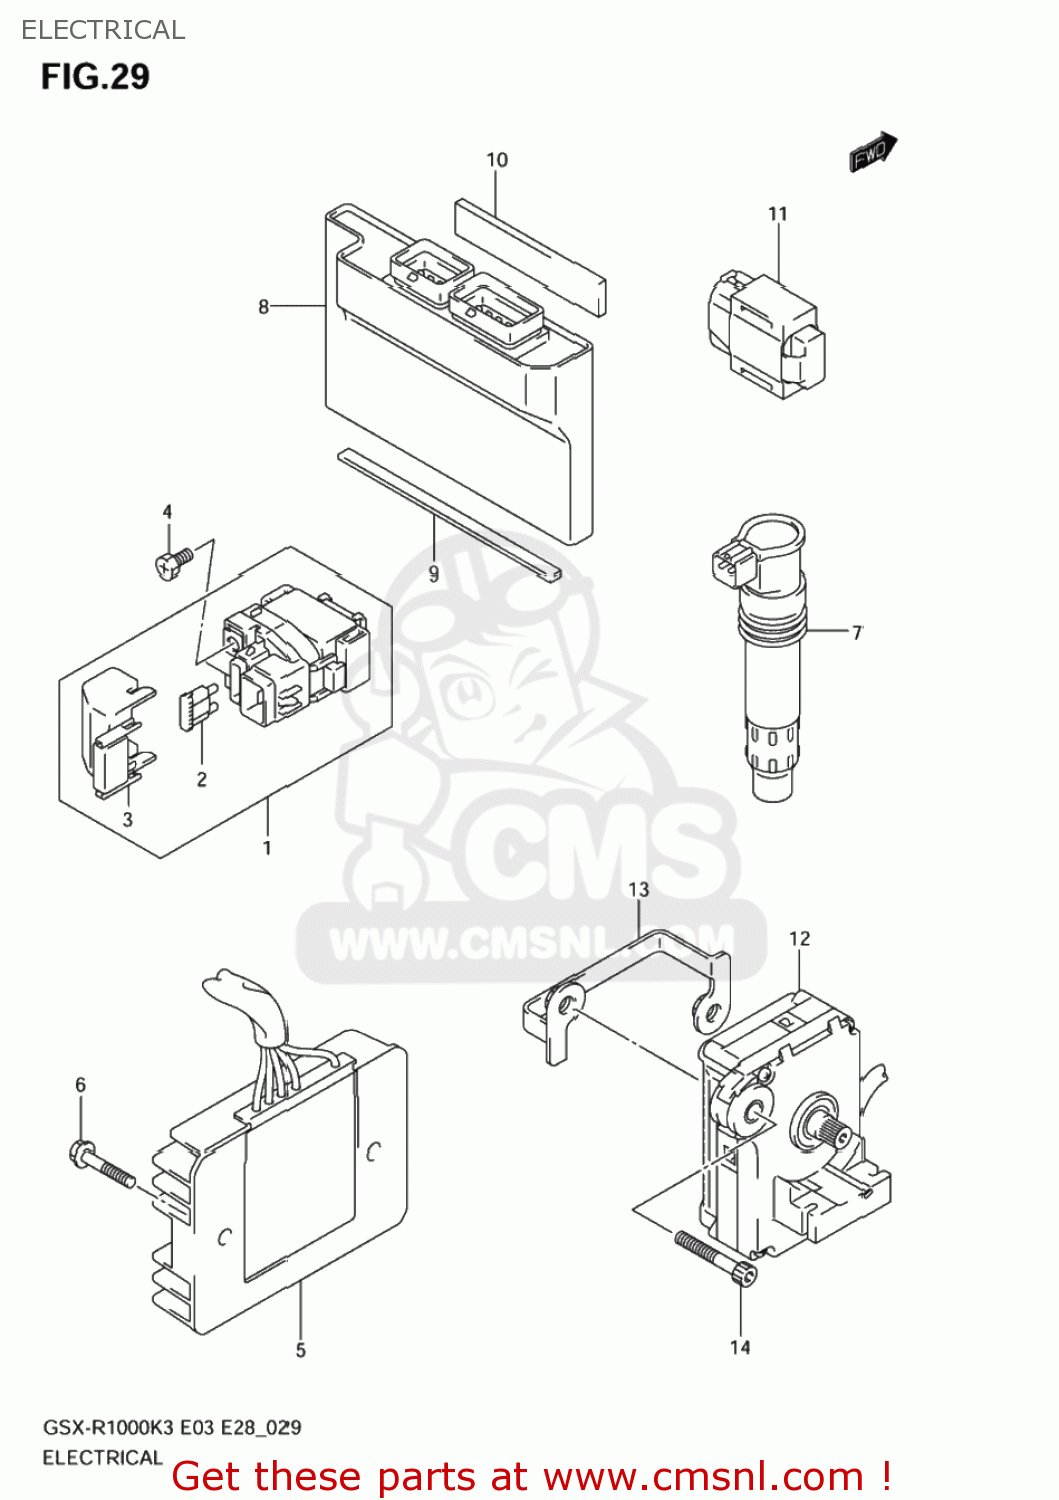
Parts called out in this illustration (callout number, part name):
1	RELAY ASSY,STARTING MOTOR
2	FUSE(30A)
3	COVER,STARTER RELAY
4	SCREW(6X8)
5	RECTIFIER ASY
6	SCREW
7	COIL ASSY,IGNITION
8	CONTROL UNIT,FI
9	CUSHION(130X10X2)
10	PROTECTOR(20X90)X4
11	SENSOR ASSY,FUEL CUT
12	ACTUATOR ASSY,EXHAUST CONTROL
13	HOLDER,ACTUATOR
14	BOLT
